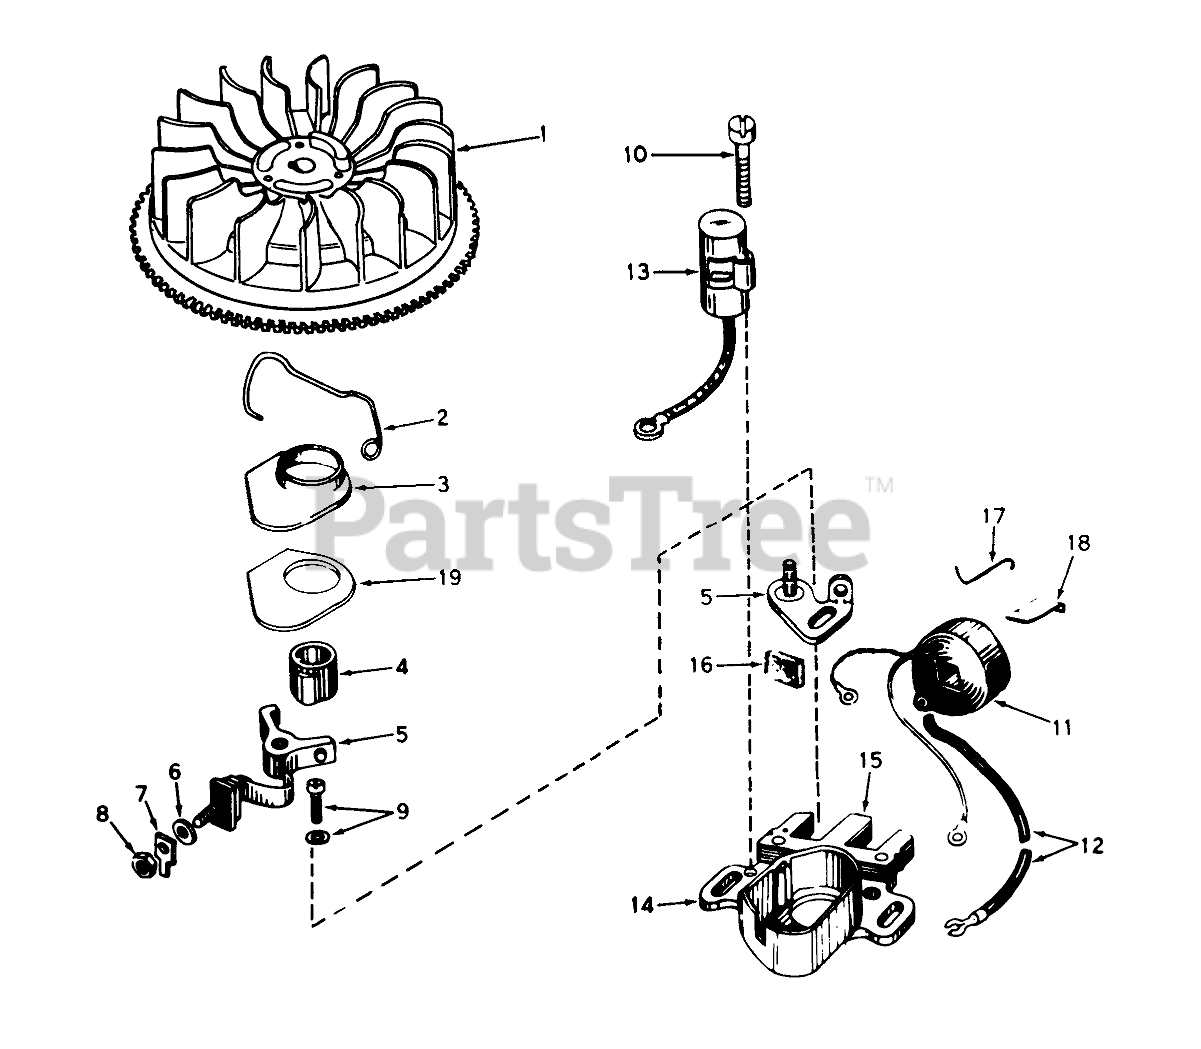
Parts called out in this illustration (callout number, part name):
1	Flywheel
2	Spring Breaker Box
3	Cover, Dust
4	Cam-Breaker
5	Breaker Assy.
7	Terminal
9	Breaker Screw
10	Condenser Screw
11	Coil Assembly (Incl. No. 12)
12	Wire, Lead
13	Condenser
14	Core & Plate
15	Stator Assembly (Incl. Nos. 5-14, 16, 17 & 18)
16	Felt,Cam Wiper
17	Clip, Coil
18	Spring Coil Wedge
19	Gasket Dust Cover
